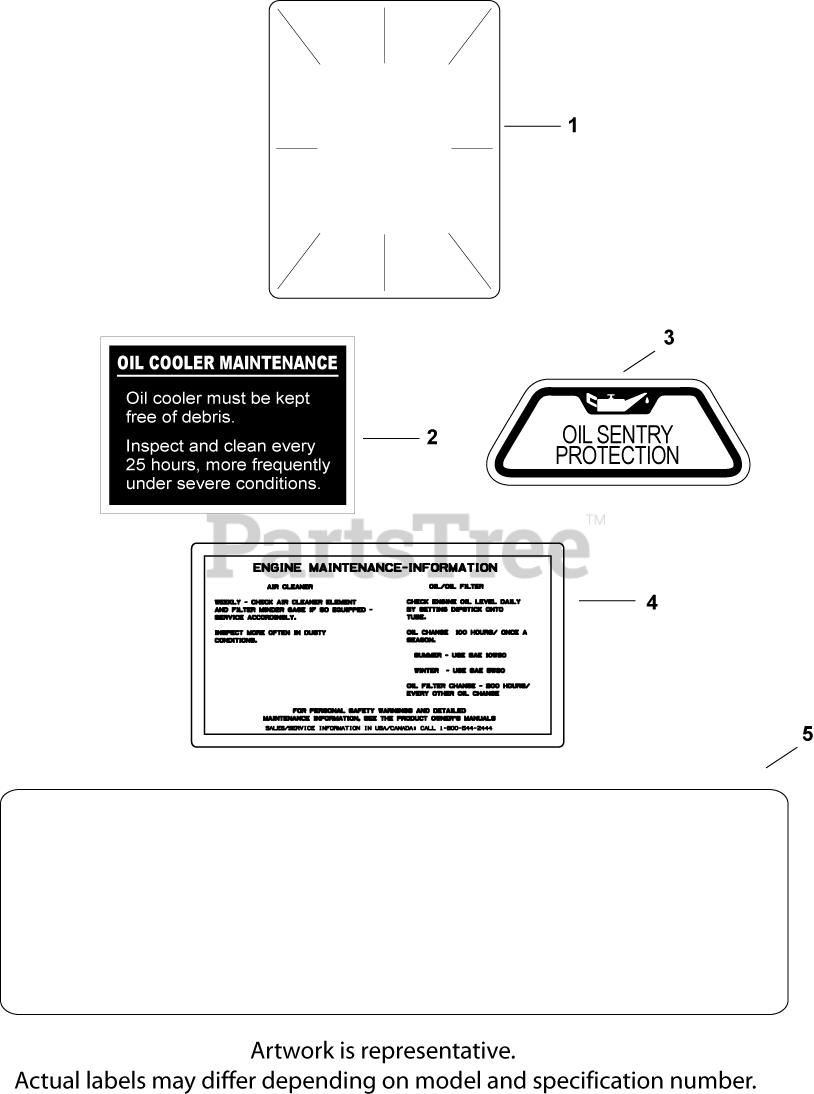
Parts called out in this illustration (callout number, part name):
1	DECAL, CLEAR LAMINATE USE 25 113 70-S
2	DECAL, OIL COOLER - (#DSC)
3	DECAL, OIL SENTRY - (#DSC)
4	DECAL, AIR CLEANER - (#DSC)
5	DECAL, 25 HP
